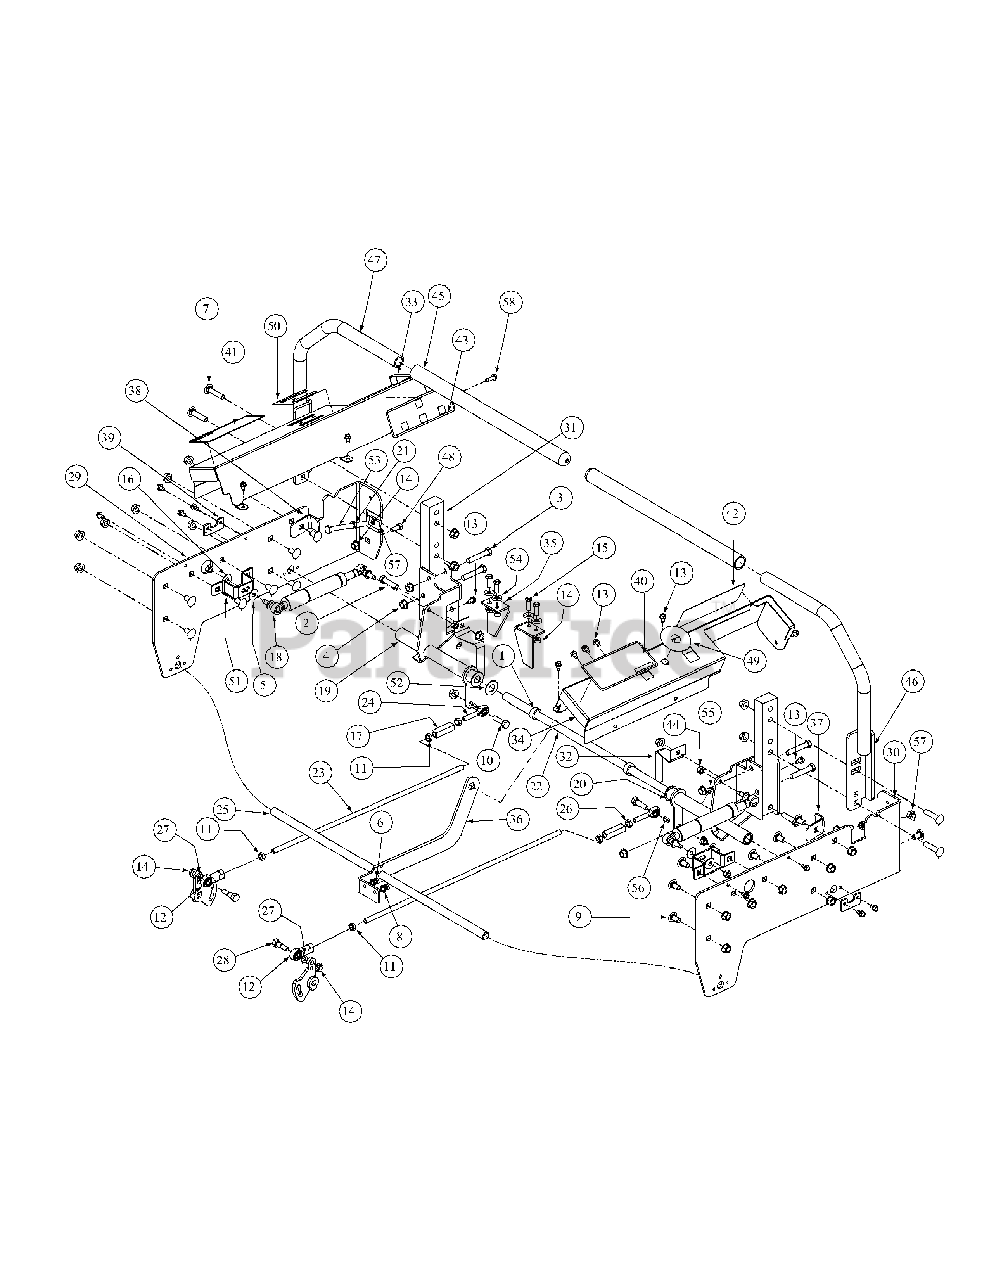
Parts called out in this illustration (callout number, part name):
1	Shaft Collar
2	HHCS, 3/8-16, 1.50
3	HHCS, 3/8-16, 2.50
4	Hex Nut, 3/8-16, Lock Flange
5	External Washer, 3/8
6	HHCS, 1/4-20, .750
7	Hex Carriage Screw, 3/8-16, 1.75
8	Lock Washer, 1/4 Zinc
9	Carriage Bolt, 3/8-16 x .75
10	Capscrew, 3/8-16 x 1-3/4
11	Hex Jam Nut, 3/8-24
12	B/Joint, 3/8-24, Right Hand Female
13	Screw, TT, 1/4-20, 0.5, Hex Index Washer
14	Nut, Lock, Hex Flange, 5/16-18
15	Hex, Cap Screw, 5/16-18 x 3/4
16	Belle Washer, .325 x .930 x .045
17	Turnbuckle
18	Cylinder Return to Neutral
19	Hub Assy, Control LH Bearing
20	Hub Assy, Control RH Bearing
21	Nut, 3/8-16, Jam
22	Shaft Control Brake Steering
23	Rod Connector 3/8 OD x 14.25
24	B/Joint, 3/8-24, Left Hand Female
25	Rear Brake Shaft
26	Nut, 3/8-24, Jam, LH Third
27	Lock Washer, 5/16
28	Screw, Shoulder Control Rod
29	Side Panel, Control, Left
30	Side Panel, Control, Right
31	Mounting Handle
32	Lever, Safety Switch
33	Control Panel, LH
34	Control Panel, RH
35	Switch Mounting Bracket, Lapbar
36	Link Mounting Control Shaft, Bracket
39	Holder Shaft, Park Brake
40	Decal , Right Hand Console
41	Decal, Left Hand Console
42	Decal Right Hand Control
43	Decal, Left Hand Control
44	Nut, Hex, Center Lock, M8
45	Grip, 1.0
46	Lapbar, Weldment, Right Handle
47	Lapbar, Weldment, Left Handle
48	HHCS, 5/16-18 x 1.0
49	Label, Ignition, 2.5 Diameter
50	Label, Control, Throttle and Choke
51	Bracket Assembly, Mount Dampener
52	Flat Washer, 5/8 Nylon
53	HHCS, 3/8-16, 3.00
54	Flat Washer, 5/16
55	Grease Fitting, 90 degree
56	Spacer, .385ID x .625 OD x .50 Lg
57	U-Nut, 3/8-16, .75
58	Screw, TT, 1/4-20 x .750
